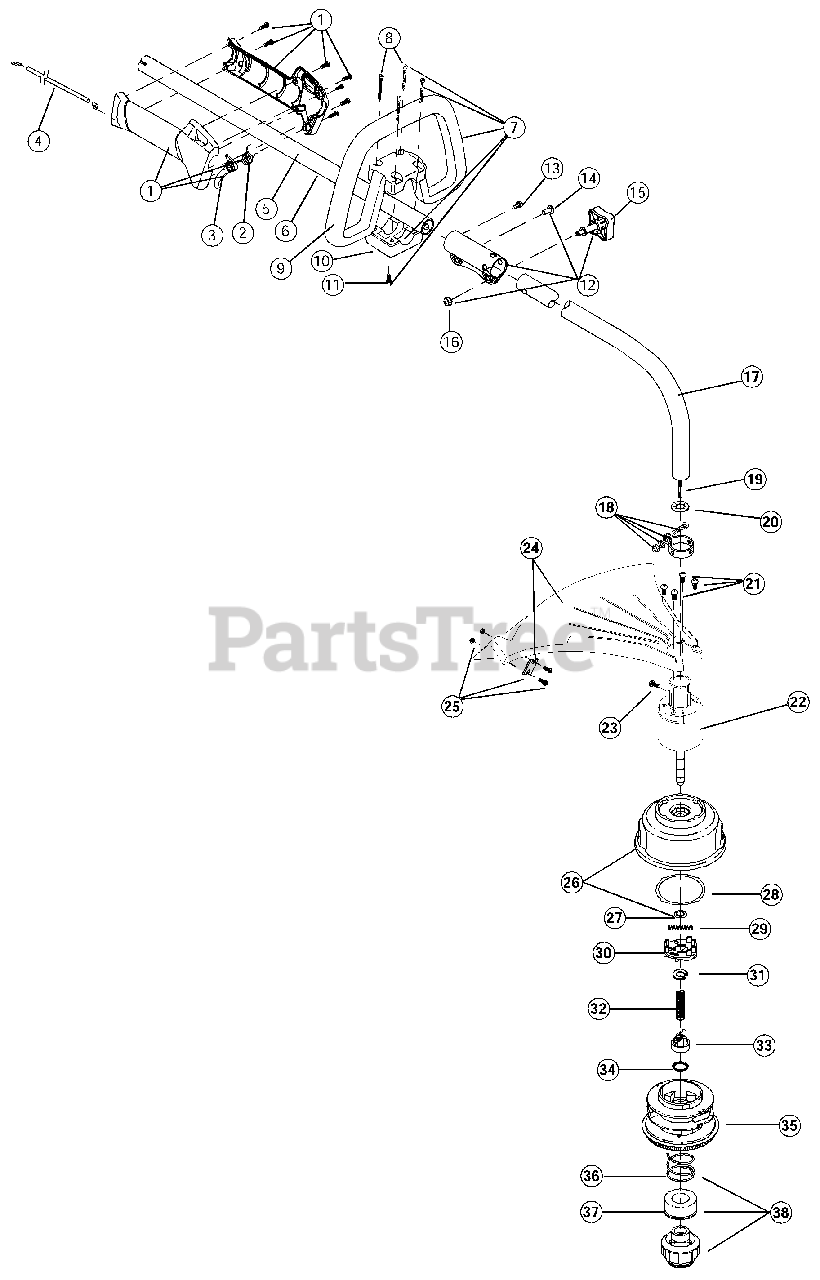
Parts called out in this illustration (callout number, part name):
1	Throttle Housing and Trigger Assembly (includes 2 & 3)
2	Throttle Trigger Spring
3	Throttle Trigger
4	Throttle Cable Assembly
5	Upper Drive Shaft Housing Assembly
6	Harness Clip
7	Deluxe D-Handle Assembly (includes 8-10)
9	Deluxe D-Handle
10	Bottom Clamp
11	Anti-Rotation Screw
12	EZ-Link Coupler (includes 13-16)
15	Adjustment Knob (includes 12)
16	Knob Retaining Nut
17	Lower Drive Shaft Housing Assembly
18	Lower Clamp Assembly
19	Lower Flexible Drive Shaft
20	Palnut
21	Shield Mounting Screw
22	Bushing Housing Assembly
23	Anti-Rotation Screw
24	Shield and Blade Assembly (includes 29)
25	Blade Assembly
26	Outer Spool and Eyelet Assembly w/ Retainer
28	Thrust Washer
29	Small Spring
30	Slider
35	Inner Reel
36	Large Spring
38	Bump Head Knob Assembly w/Spring & Foam Seal
